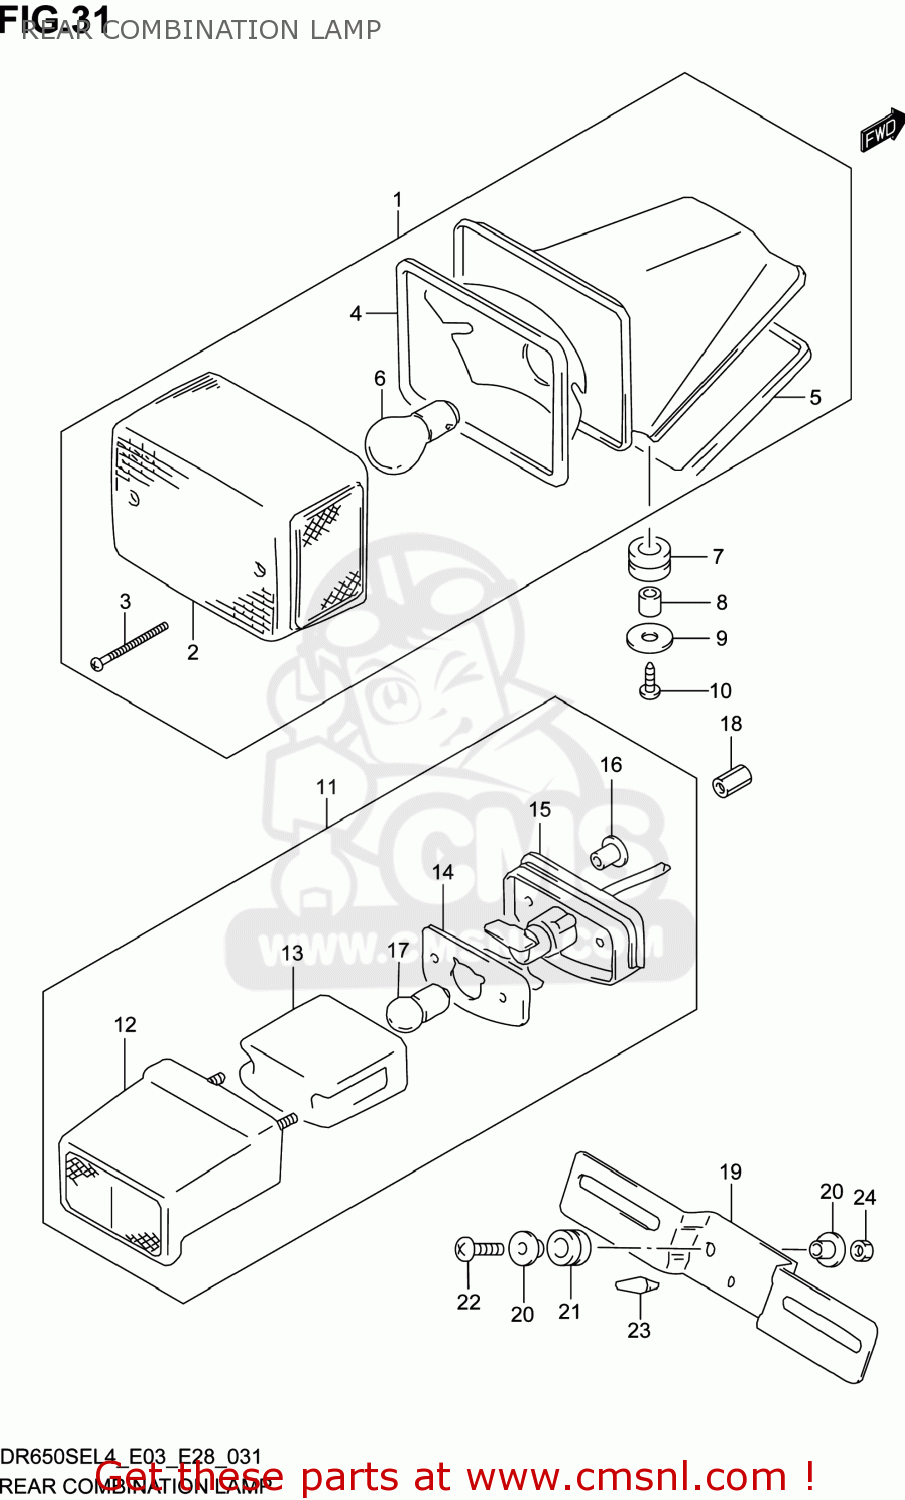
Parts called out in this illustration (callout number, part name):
1	LAMP ASSY,RR COMBINATION
2	LENS,TAIL LAMP
3	SCREW(4X45)
4	GASKET,LENS (NAS)
5	GASKET (NAS)
6	BULB(12V21/5W)
7	CUSHION
8	SPACER(6.1X8X9.5)
9	WASHER(6.5X20X1.6)
10	SCREW
11	LAMP ASSY,LICENSE
12	COVER,LICENSE
13	LENS
14	GASKET,LICENSE LAMP (NAS)
15	CUSHION
16	SPACER
17	BULB(12V5W,BF150-40160A)
18	NUT
19	BRACKET,LICENSE PLATE
20	WASHER
21	CUSHION
22	SCREW
23	CUSHION
24	NUT
